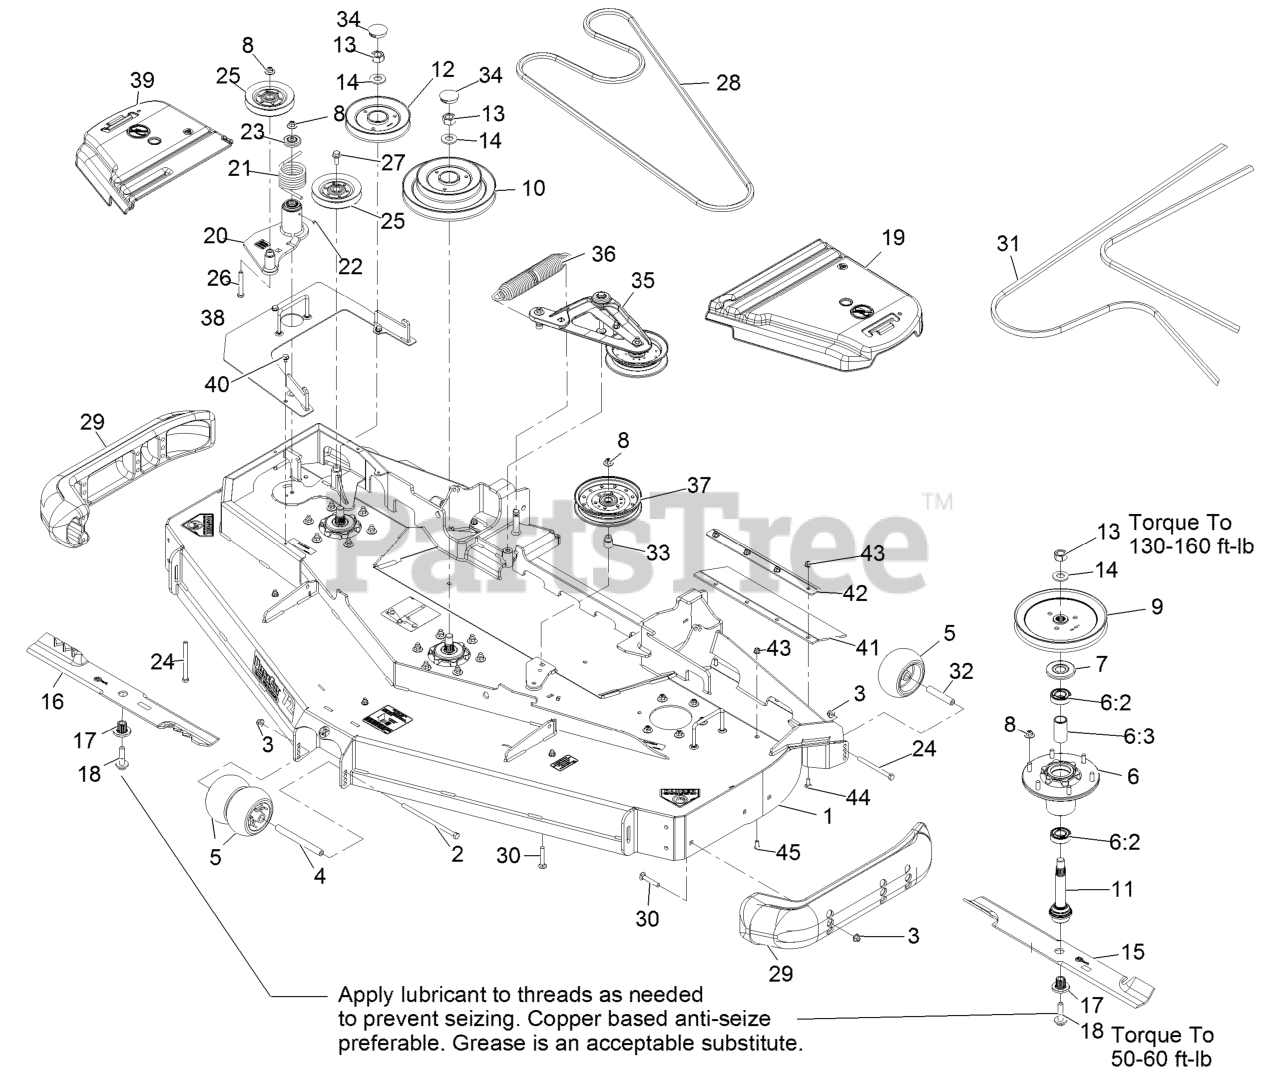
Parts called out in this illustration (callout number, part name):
1	DECK-RD72 NLZ, W/DECALS
2	SCREW-HH
3	NUT-HF, NI
4	SPACER-WHEEL
5	ROLLER-SCALP, ANTI
6	ASM-CUTTER HSG WITH BEARINGS
6:2	BEARING-BALL
6:3	SPACER-BEARING
7	GUARD,BEARING TOP .989
8	Nut-Nyloc 3/8-16 Flg
9	SHEAVE,BLADE DRIVE 8.74
10	SHEAVE, DOUBLE 72RD
11	ASM-SPINDLE AND SEAL
12	SHEAVE-RD REV DRIVE SERIE
13	NUT-HEX
17	BUSHING,SPLINED
18	SCREW,SEMS 1/2-20 X 2.19
19	COVER-BELT, LH
20	IDLER ASM
21	SPRING-TORSION
22	FITTING-GREASE
23	GUARD-TOP
24	SCREW-HH
26	SCREW-HH
27	SCREW-HHF
29	SKID-BUMPER, DECK
30	Bolt-Carriage 3/8-16 X 2 1/4
31	BELT
32	TUBE-SPANNER
33	BUSHING-IDLER
34	PLUG,BLACK NYLON 1.75
35	DECK IDLER ASM
36	SPRING-EXTENSION
38	COVER-REVERSE DRIVE
39	COVER-BELT, RH
41	GUARD-TIRE
42	SUPPORT-OUTER FLAP
43	NUT-HF, NI
44	SCREW-CARR
45	SCREW-HSBH
